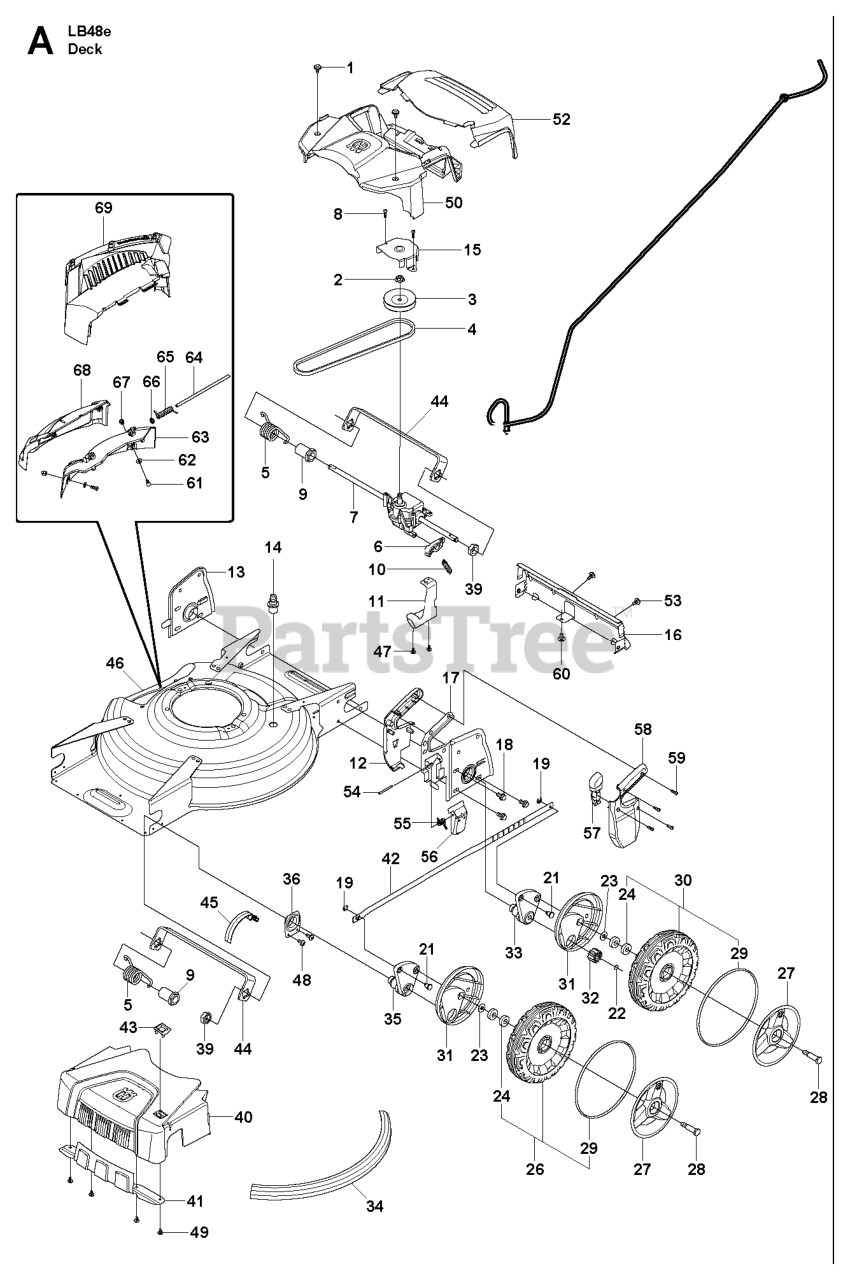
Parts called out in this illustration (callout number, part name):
1	SCREW ITXPANTT M5X10 ZPB (A00
4	BELT WRAPPED V-BELT Z 29.5
8	SCREW ITXPANT T50X16 ZN/FE (A
19	FASTENER
24	BALL BEARING
46	CHASSIS 48S A009 PAINTED
47	SCREW ITXPANTT M5X10 ZPB (A00
48	SCREW ITXPANTT M5X10 ZPB (A00
49	SCREW ITXPANTT M5X10 ZPB (A00
53	SCREW ITXPANTT M5X10 ZPB (A00
59	SCREW ITXPANT T50X16 ZN/FE (A
60	SCREW ITXPANTT M5X10 ZPB (A00
